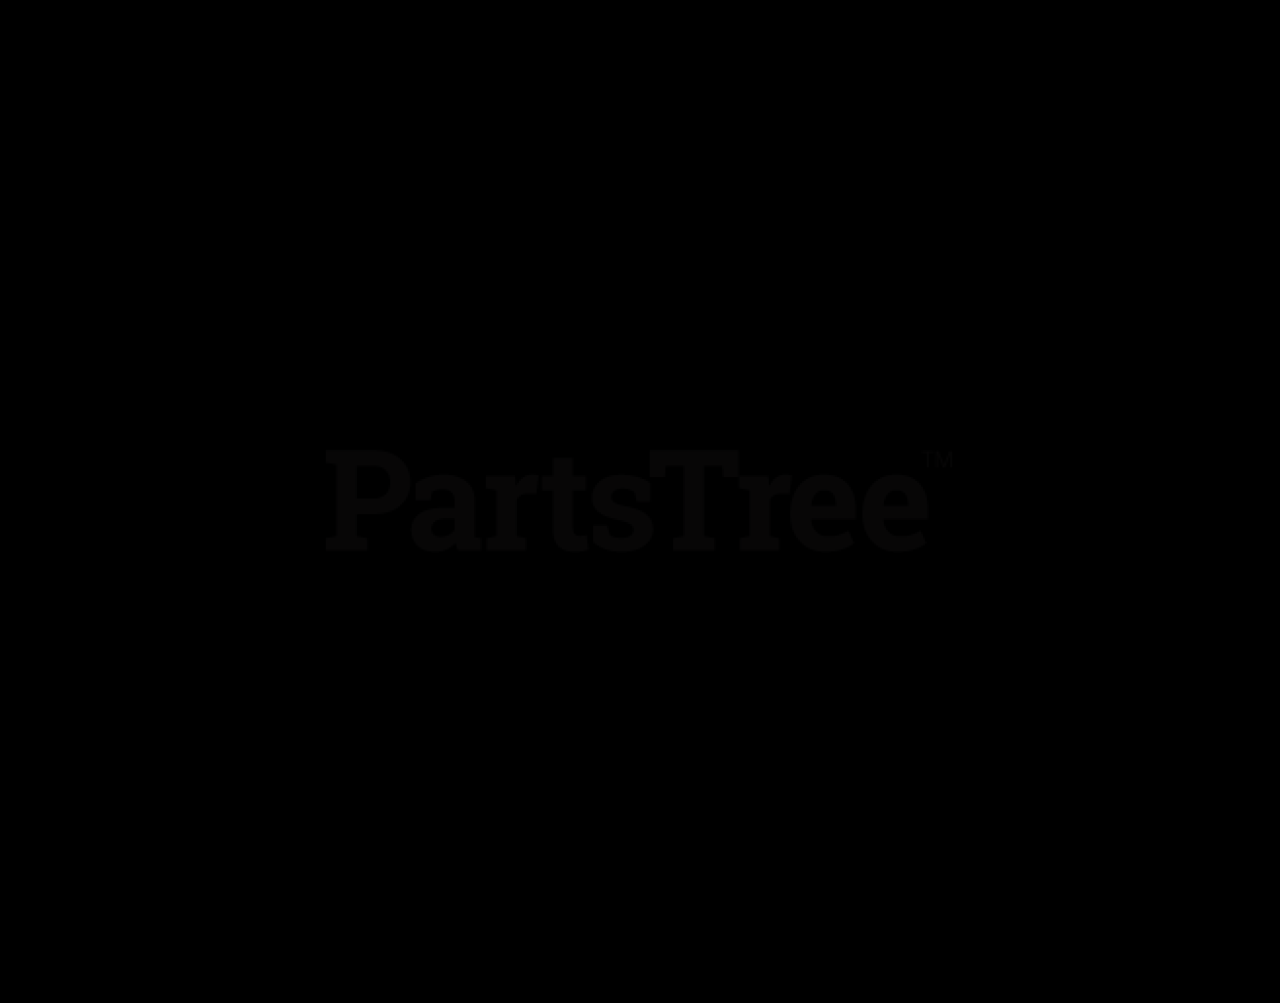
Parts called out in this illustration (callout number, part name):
1	Assembly, Steering Rod .38 Rod x 21.65
2	Washer, Flat Steel .408 x .812 x .065
3	Bolt, Hex .31-18 x 1.75 Grade 5
4	Nut, Hex Jam .375-16
5	Bolt, Hex .375-16 x 1.75
6	Weldment, Control Arm
7	Bushing, Flange
8	Bushing, Eccentric .31 x .75 x .97
9	Nut, Locking Top Flange .31-18
10	Handle Weldment, Left Hand
11	Bushing, Flange Nylon .762 x 1.48 x .44
13	Grip, Handlebar
14	Bushing .625 x .75 x .50
15	Bracket, Stop Right Hand
16	Bracket, Stop Left Hand
17	Screw, Tapping .38-16 x .75 Hex Washer Head
18	Bolt, Hex .31-18 x .75 Grade 5
19	Washer, Locking .38 x .094 Regular
20	Key, Woodruff .13 x .63
21	Washer, Wave
22	Weldment, Pivot Arm
23	Nut, Locking Top Flange .38-16
24	Screw, Tapping .38-16 x .50 Hex Washer Head
25	Nut, Locking Jam Center .375-16
26	Weldment, Return to Neutral/Damper/Rod End
27	Washer, Flat Steel .63 x 1.005 x .062
28	Washer, Locking .31 x .078
29	Bolt, Hex .31-18 x 1.25 Grade 5
30	Damper, Control
31	Spacer .318 x .43 x .375
32	Washer, Flat Steel .38 x .875 x .083
33	Tube, .88 ID x 1.00 OD x 10.7
34	Washer, Flat Steel .328 x 1.00 x .094
35	Stud, Ball
36	Strip Cowl
